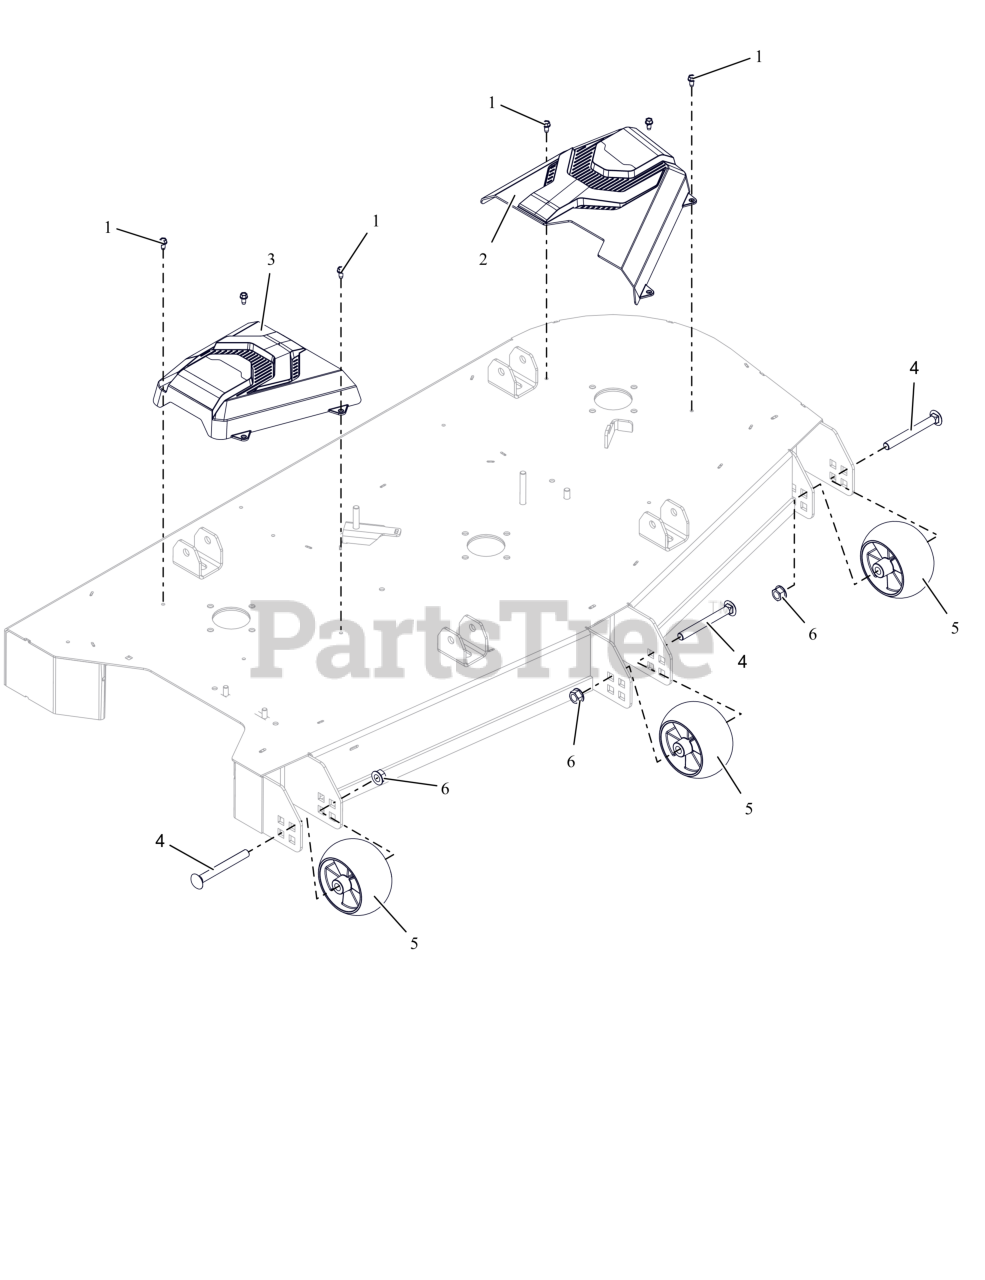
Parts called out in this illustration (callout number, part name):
1	SCR-TAP .25-20X.50 HWH ZCC
2	COVER- BELT LH
3	COVER- BELT RH
4	BOLT, RHNS .50-13X4.50 G5 ZCC NS
5	WHEEL, ANTI SCALP - 5X3 CTR W/RIBS
6	NUT-LK-CTR-FLG .500-13 GG ZCC
